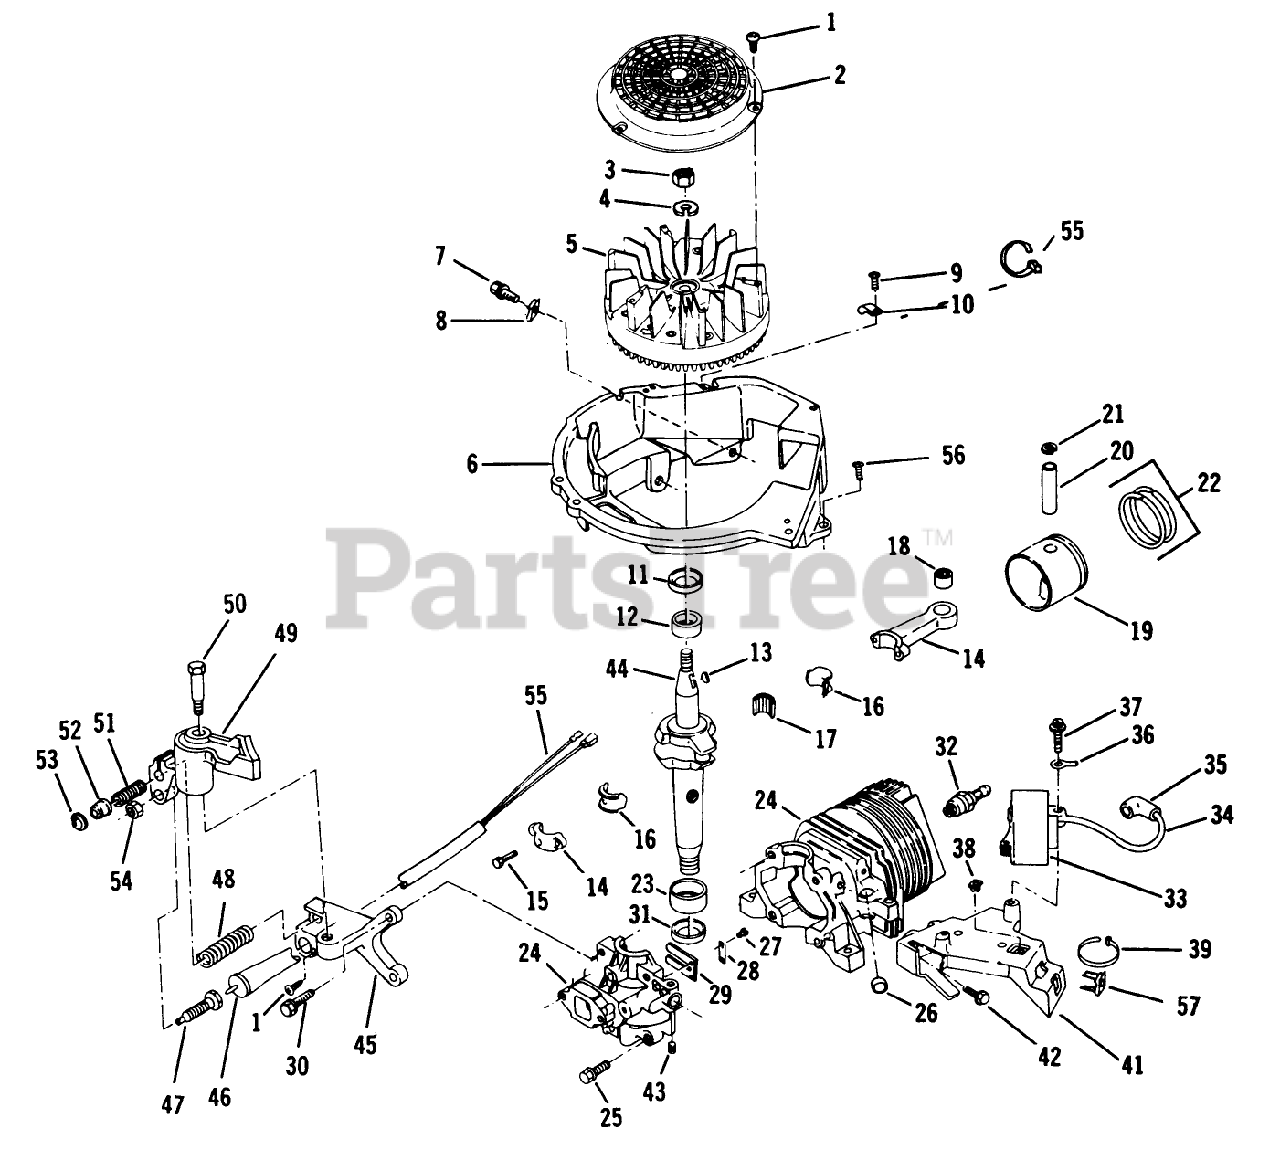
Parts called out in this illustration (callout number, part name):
1	SCREW F
2	SCREEN F'WHEEL S
3	NUT
5	FLYWHEEL ASSY F
7	SCREW-SEMS
9	SCREW F
12	BEARING V
13	KEY
15	SCREW-HSH
16	LINER ASM
18	BEARING AY F
21	RING-RETAINING
23	BEARING V
25	SCREW S
26	PLUG-CORE VF
28	PLATE-BACKUP, REED
31	SEAL-OIL
34	HT LEAD&COVER XEV
36	TERMINAL S
38	NUT-CLIP
41	BRACKET S
45	BRACKET-BRAKE F
47	PLUNGER S
48	SPRING-BRAKE
51	SPRING
52	ACTUATOR-LEVER, BRAKE
53	RETAINER S
56	SCREW F
57	NUT-CLIP
57	NUT-SPEED
